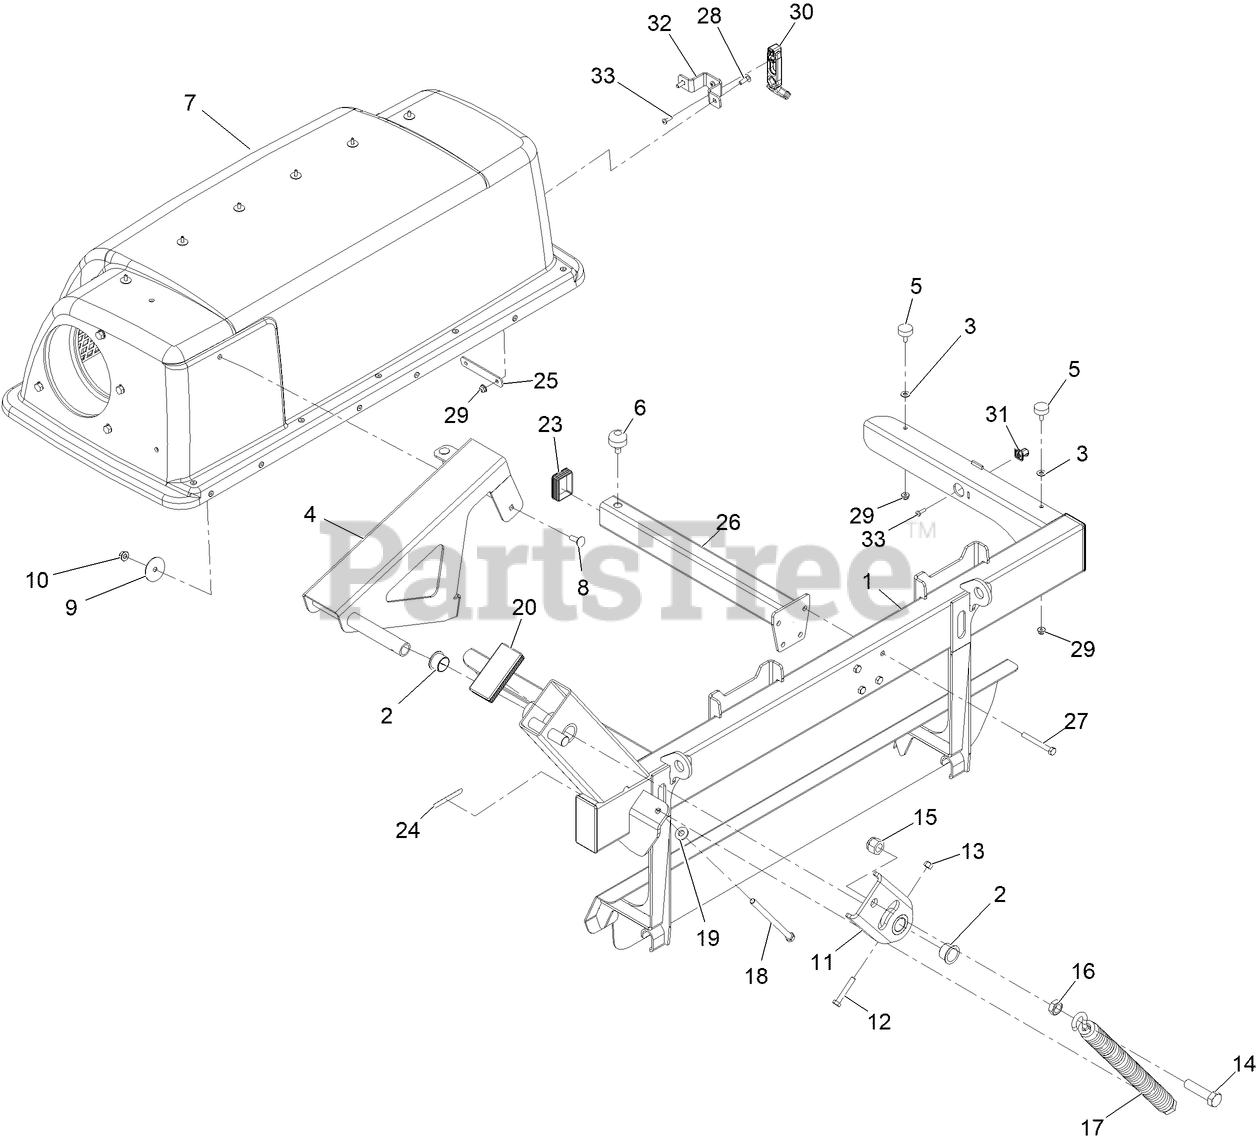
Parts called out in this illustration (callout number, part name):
1	FRAME-BAGGER
2	BUSHING
3	WASHER-FLAT
4	HOOD PIVOT ASM
5	BUMPER-RUBBER
6	BUMPER-RUBBER
7	ASM-Hood,Twin Bagger
8	BOLT-CARR
10	NUT-HF, NI
11	BELLCRANK ASM
12	SCREW-HH
13	NUT-LOCK, NI
14	Screw-HH
15	NUT-LOCK, NI
16	NUT-JAM
17	SPRING-EXTENSION
18	BOLT-TAP, HH
19	WASHER-BELLEVILLE
20	CAP-END
23	CAP-END
24	DECAL-WARNING
25	STRAP-BAGGER HOOD LATCH
26	ASM-Center Bagger Support [black]
27	SCREW-HH
28	SCREW-CARR
30	LATCH-RUBBER
31	LATCH-KEEPER
32	BRACKET-BAGGER HOOD LATCH
33	SCREW-PPH
